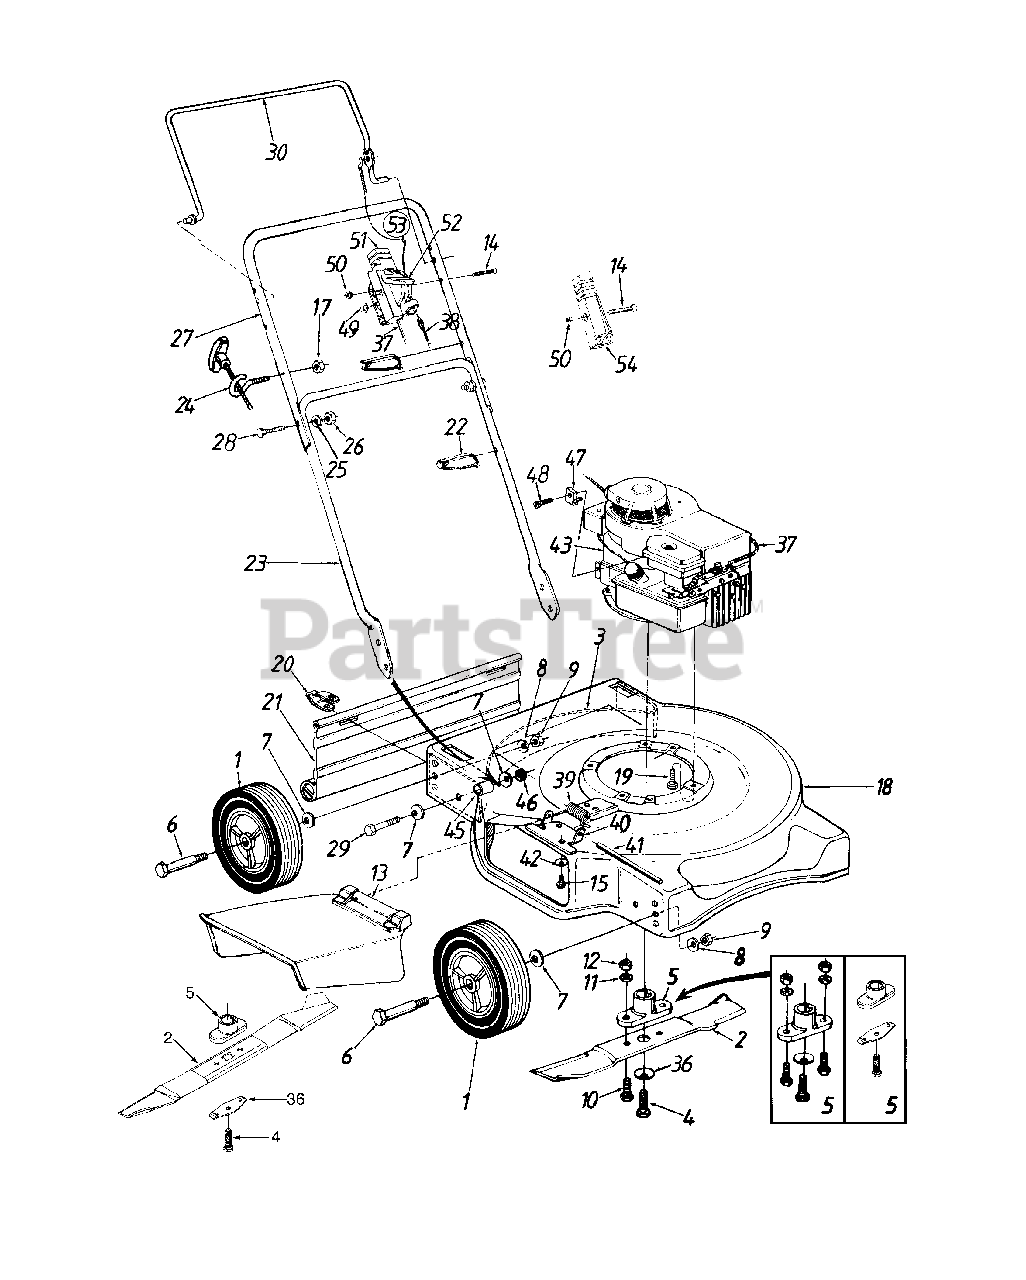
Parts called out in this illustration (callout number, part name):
1	Wheel Ass'y. Complete 6", Rib Tread
2	20" Blade
5	Blade Adapter Kit
6	Axle Bolt
7	Bell-Wash. .380" I.D. x .88"
8	Bell-Wash. .39" I.D. x 1.13"
9	Hex Nut 3/8-16 Thd.
10	Hex Bolt 3/8-24 x 1" Lg.
11	L-Wash. 3/8" I.D.
12	Hex Nut 3/8-24 Thd.
13	Chute Deflector Ass'y.
14	Oval C-Sunk Scr.
15	Self-Tap Scr. 1/4-20 x .5" Lg.
17	Hex L-Nut 1/4-20 Thd.
20	Hinge Clip
21	Rear Flap 16.69" Lg.
22	Cable Tie
24	Rope Guide
25	L-Wash. 5/16" I.D.
26	Hex Nut 5/16-18 Thd.
29	Hex Bolt 3/8-24 x 1.5" Lg.
36	Bell-Wash. .39" I.D.
37	Throttle Control Wire-51"
38	Control Cable-36"
39	Torsion Spring
40	Adapter Plate
41	Hinge Pin
42	Bell-Wash. 1/4" I.D.
43	Engine
45	Spacer
46	Hex L-Nut 3/8-24 Thd.
47	Casing Clamp (B&S)
48	Hex Wash. Hd. Scr. #10-32 x .62" Lg.
49	Spring Wash. .66" I.D.
50	Hex L-Nut 1/4-20 Thd.
51	Throttle Body
52	Throttle Lever
53	Throttle Box Comp.
54	Control Cable Box
